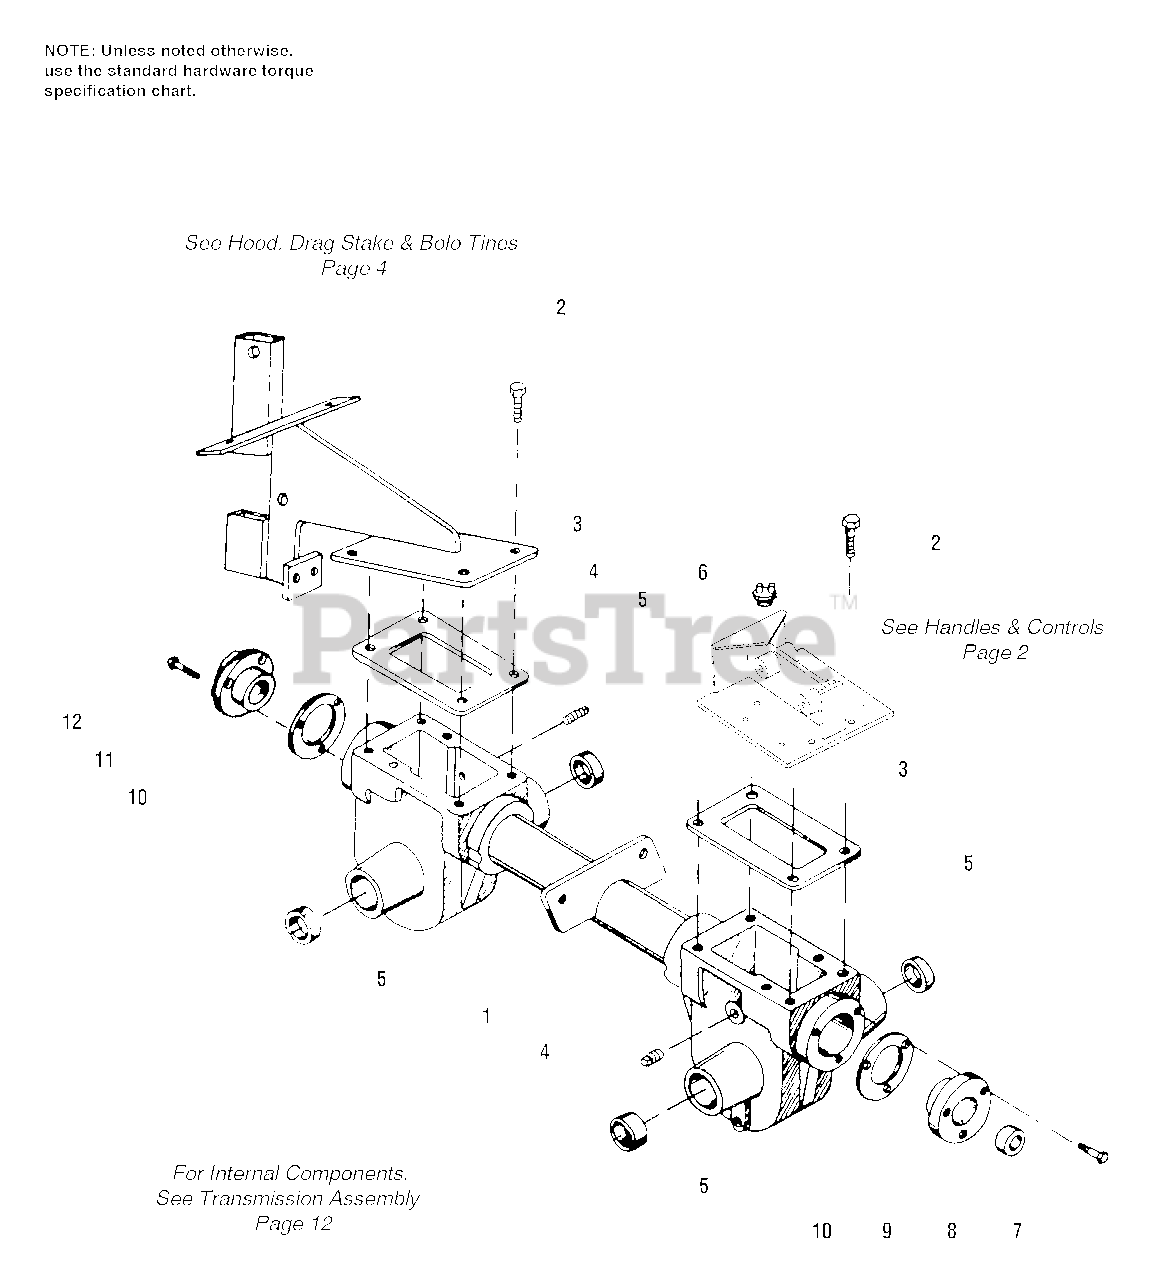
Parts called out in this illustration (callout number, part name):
1	TRANSMISSION ASSEMBLY
2	BOLT, Hex Flange Hd, 5/16"-18 x 3/4", Grade 5
3	GASKET, Tiller Housing & Transmission Cover
4	PIPE PLUG, Soc Hd, 1/4"-18, Oil Level
5	SEAL, Tiller Housing
6	PLUG, Oil Fill
7	BOLT, Hex Flange Hd, 1/4"-20 x 3/4"
8	OIL SEAL, Drive Shaft
9	CAP, Front Bearing
10	GASKET, Front Rear Bearing Cap
11	CAP, Rear Bearing
12	BOLT, Hex Flange Hd, 1/4"-20 x 7/8"
